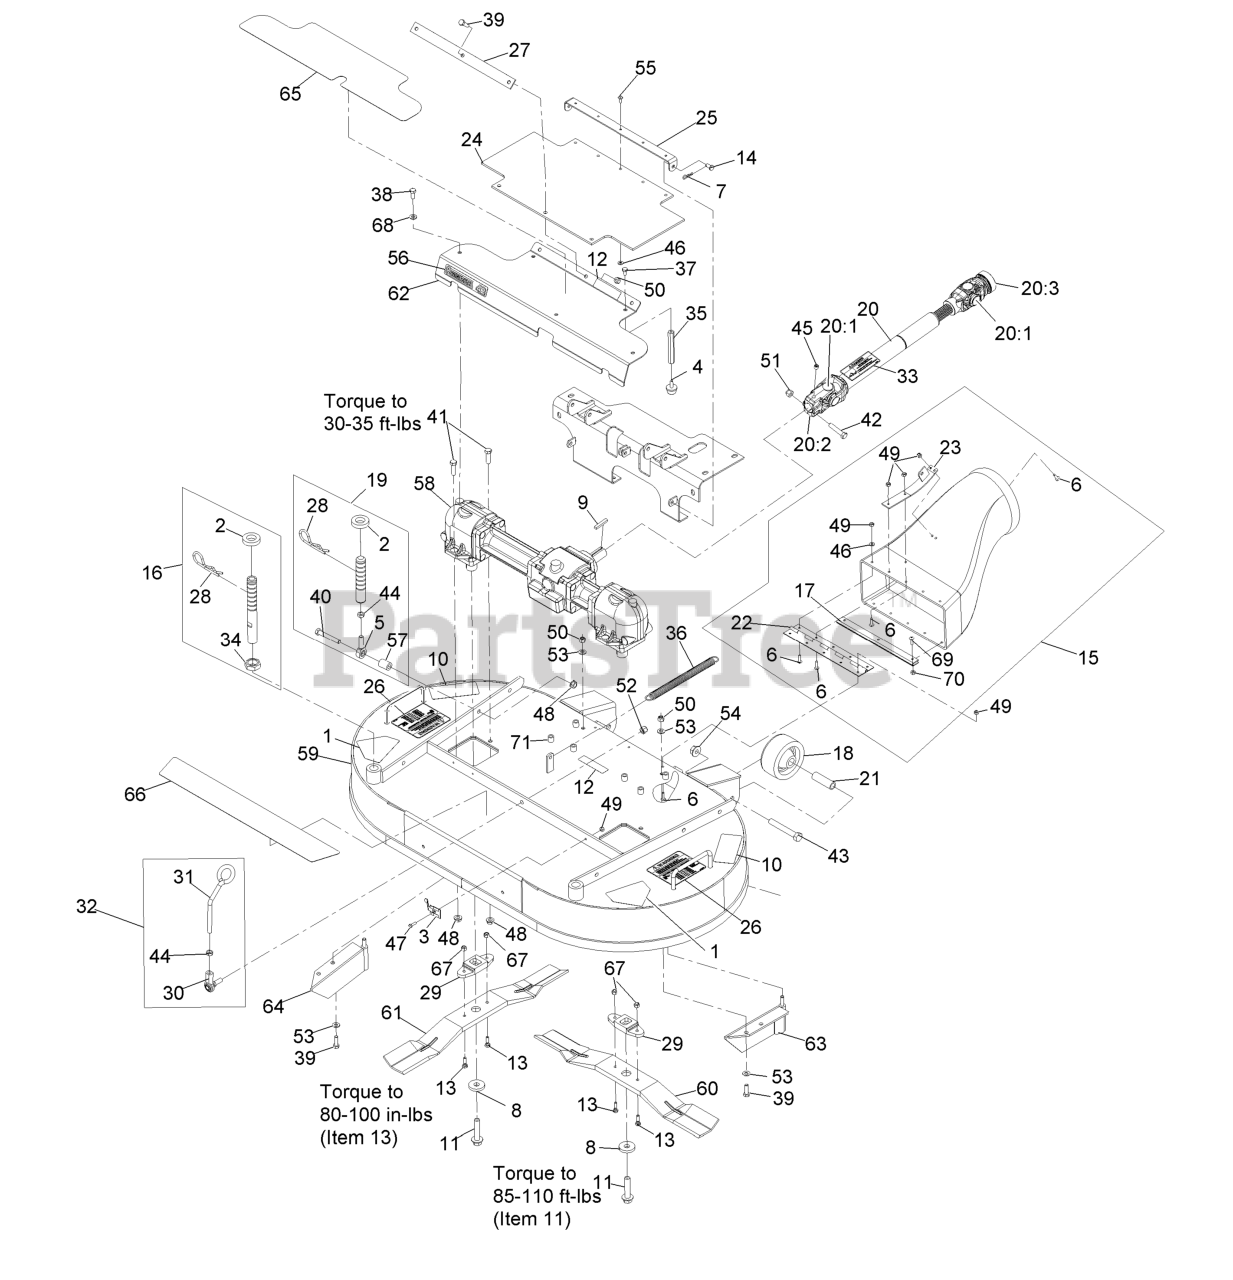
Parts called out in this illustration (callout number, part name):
1	DECAL-DANGER
2	SPACER-DECK SUPPORT
3	CLIP-DECK, HOLD UP ROD
4	BUMPER-RUBBER
5	BALLJOINT
6	SCREW-HEAD, TRUSS
7	PIN-COTTER
9	KEY-SQUARE
10	DECAL-TORQUE
11	BOLT-BLADE
12	DECAL-COVER, MISSING
13	BOLT-SHEAR
14	PIN-CLEVIS
15	DISCHARGE TUBE ASM
16	FRONT DECK HEIGHT ADJUST
17	GUARD-PLENUM
18	ROLLER-DECK
19	REAR DECK HEIGHT ADJUST A
20	DRIVE SHAFT ASM
20:2	YOKE-KEYED
20:3	YOKE-QUICK DISCONNECT
21	SPACER-ROLLER
22	HINGE-PIANO
23	MOUNT-SPRING
24	GUARD-PTO
25	BRACKET-GUARD, PTO
27	STRAP-DRIVE, LINE COVER
28	PIN-CUT HEIGHT
29	DRIVER-BLADE
30	BALLJOINT-RH
31	LATCH-DECK
32	DECK LATCH ASM
33	DECAL-DRIVELINE
34	NUT-JAM
35	STAND-OFF
36	SPRING-EXTENSION
37	SCREW-HH
38	SCREW-HH
39	SCREW-HH
40	SCREW-HH
41	SCREW-HH
42	SCREW-HH
43	SCREW-HH
44	NUT-HEX
45	SCREW-SET, HSH
46	WASHER-FLAT
48	NUT-HHF, WHIZ
49	NUT-LOCK, NI
50	NUT-LOCK, NI
51	NUT-LOCK, NI
52	NUT-LOCK
53	WASHER-SPRING
54	NUT-HHF
55	RIVET-BLIND
56	DECAL,COMMERCIAL 42
57	TUBE-INTERLOCK
58	GEARBOX ASM
59	DECK ASM
60	BLADE,22 INCH LH
61	BLADE,22 INCH RH
62	ASM,GEARBOX COVER 42 W/DE
63	BAFFLE-LH
64	BAFFLE-RH
65	PAD-ANTI SKID
66	PAD-SKID, ANTI
67	NUT-LOCK, NI
68	WASHER-PLAIN
69	BOLT-CARR
70	NUT-LOCK, NI
71	NUT-CLINCH
